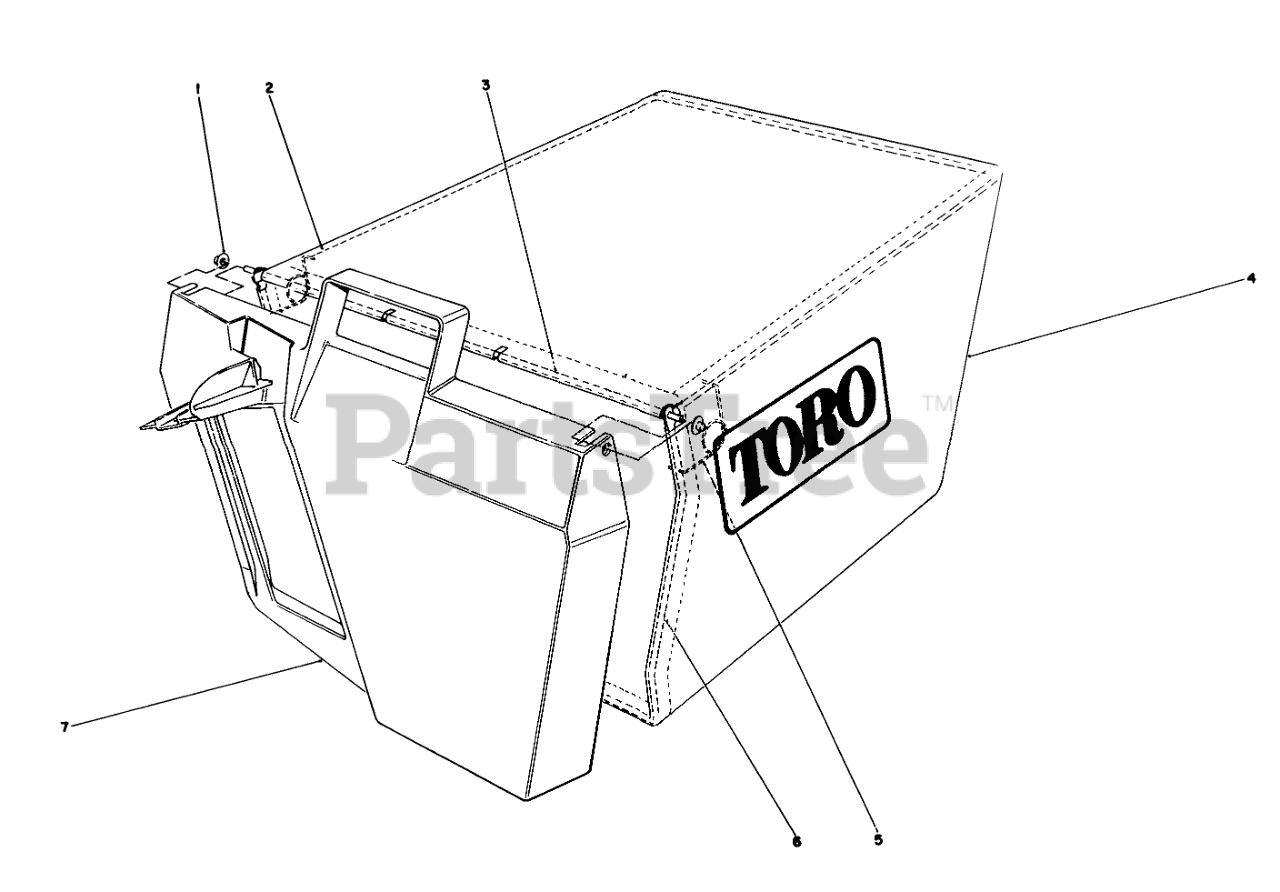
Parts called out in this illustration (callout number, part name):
1	NUT-PUSH
2	FRAME-BAG, UPPER
3	HINGE-DOOR, BAG
4	BAG-GRASS
5	SPRING
6	BAG FRAME
7	BAG DOOR
